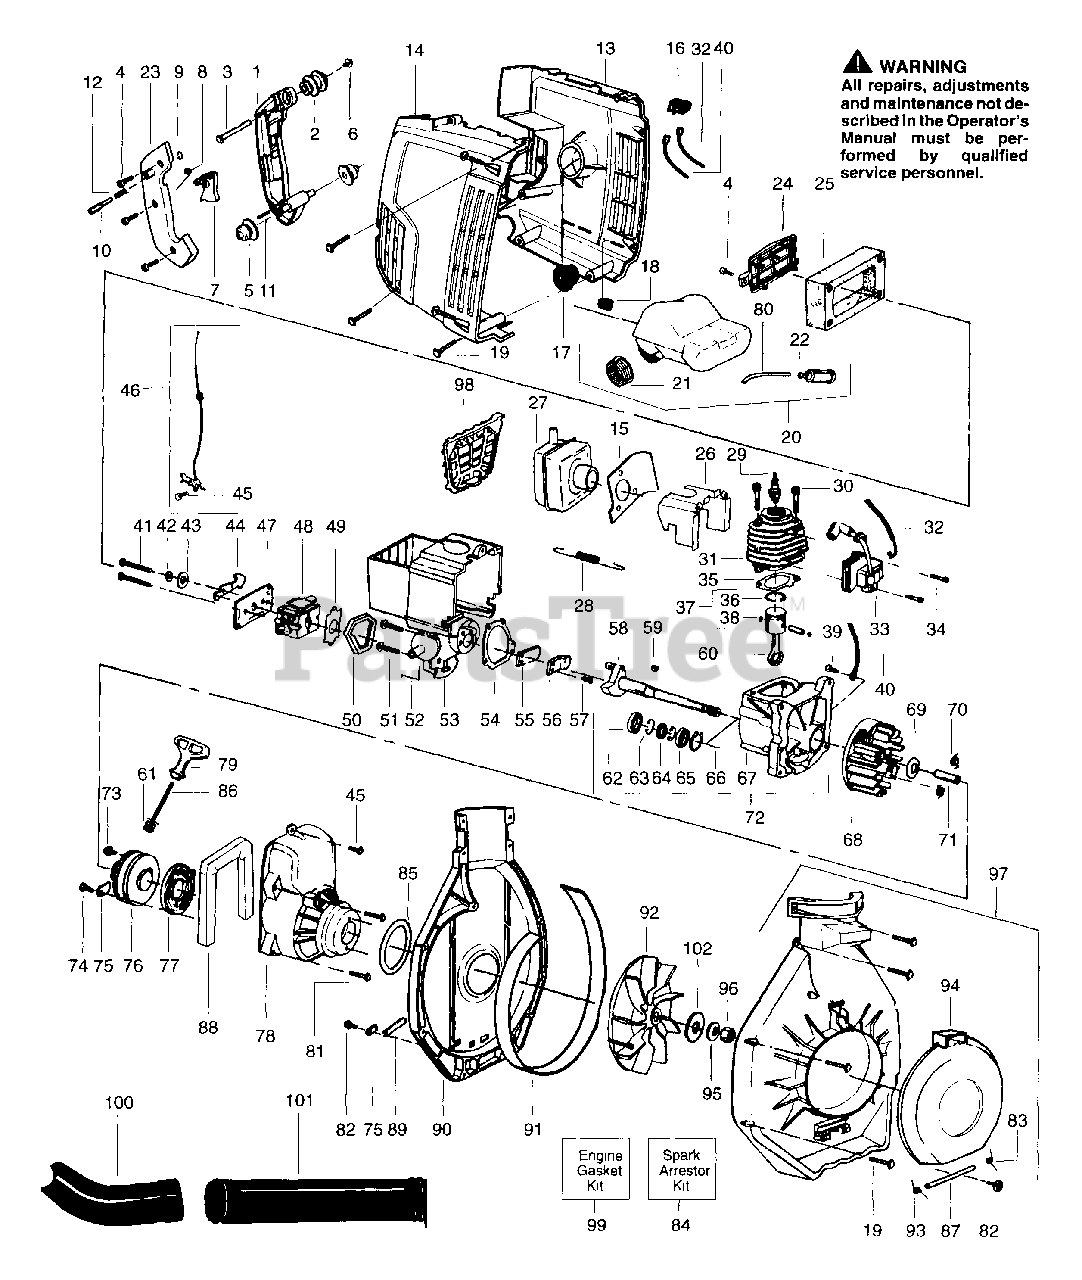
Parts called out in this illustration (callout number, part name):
1	Handle Kit
2	Isolator
3	Spacer - Isolator
5	Isolator - Handle (Rear)
8	Spring - Lever Return
9	"C" Clip - Throttle Lock
10	Throttle Lock Button
11	Pin - Handle
12	Spring - Throttle
13	Shroud - Left
14	Shroud - Right
15	Heat Shield
16	Switch Kit
17	Isolator - Engine Mount
18	Isolator Tank
20	Fuel Tank Ass'y
21	Fuel Cap Ass'y
22	Fuel Pick-up Ass'y
23	Handle Cover Ass'y
24	Cover - Filter
25	Air Filter (Foam)
26	Air Baffle
27	Muffler Kit
28	Spring - Muffler
29	Spark Plug (RCJ-8Y)
31	Cylinder Kit
32	Lead Wire (Switch)
33	Ignition Module
35	Gasket - Cylinder
36	Piston Ring
37	Piston Kit
38	Retainer
40	Ground Wire (Switch)
43	Spacer - Choke
44	Choke Shutter
46	Cable Assembly
47	Plate - Air Filter Mtg
48	Carburetor Ass'y Kit
49	Gasket - Carb
50	Seal - Foam/Reed Block
52	Ground Wire (Static)
53	Reed Block/Heat Shield
54	Gasket - Reed Block/C'case
55	Reed Valve
56	Reed Stop
58	Crankshaft Ass'y
59	Flywheel Key
60	Connecting Rod Ass'y
61	Rope Kit
62	Inner Bearing
63	Retaining Ring
64	Crankshaft Seal
65	Outer Bearing
66	Retaining Ring (Shaft)
67	Crankcase Ass'y
68	Flywheel Ass'y
69	Washer
70	Spring - Starter Dog
71	Spacer - Flywheel
72	Crankcase/Crankshaft Assy
75	Retainer
76	Starter Pulley Kit
77	Starter Spring
78	Fan Housing Kit
79	Starter Handle
80	Line Kit
83	Spring - Torsion (Left)
84	Spark Arrestor Kit
85	"O" Ring - Seal
86	Eyelet - Flange
87	Pin - Pivot
88	Sponge - Air Dam
89	Tube - Rope Retainer
90	Blower Housing (Upper)
91	Band - Blower Hsg
92	Impeller Ass'y
93	Spring - Torsion (Right)
94	Inlet Door
95	Washer - Conical
97	Blower Housing (Lower)
98	Muffler Guard Kit
99	Gasket Kit
100	Nozzle - Concentrator
101	Blower Tube (Upper)
102	Washer - Impeller
